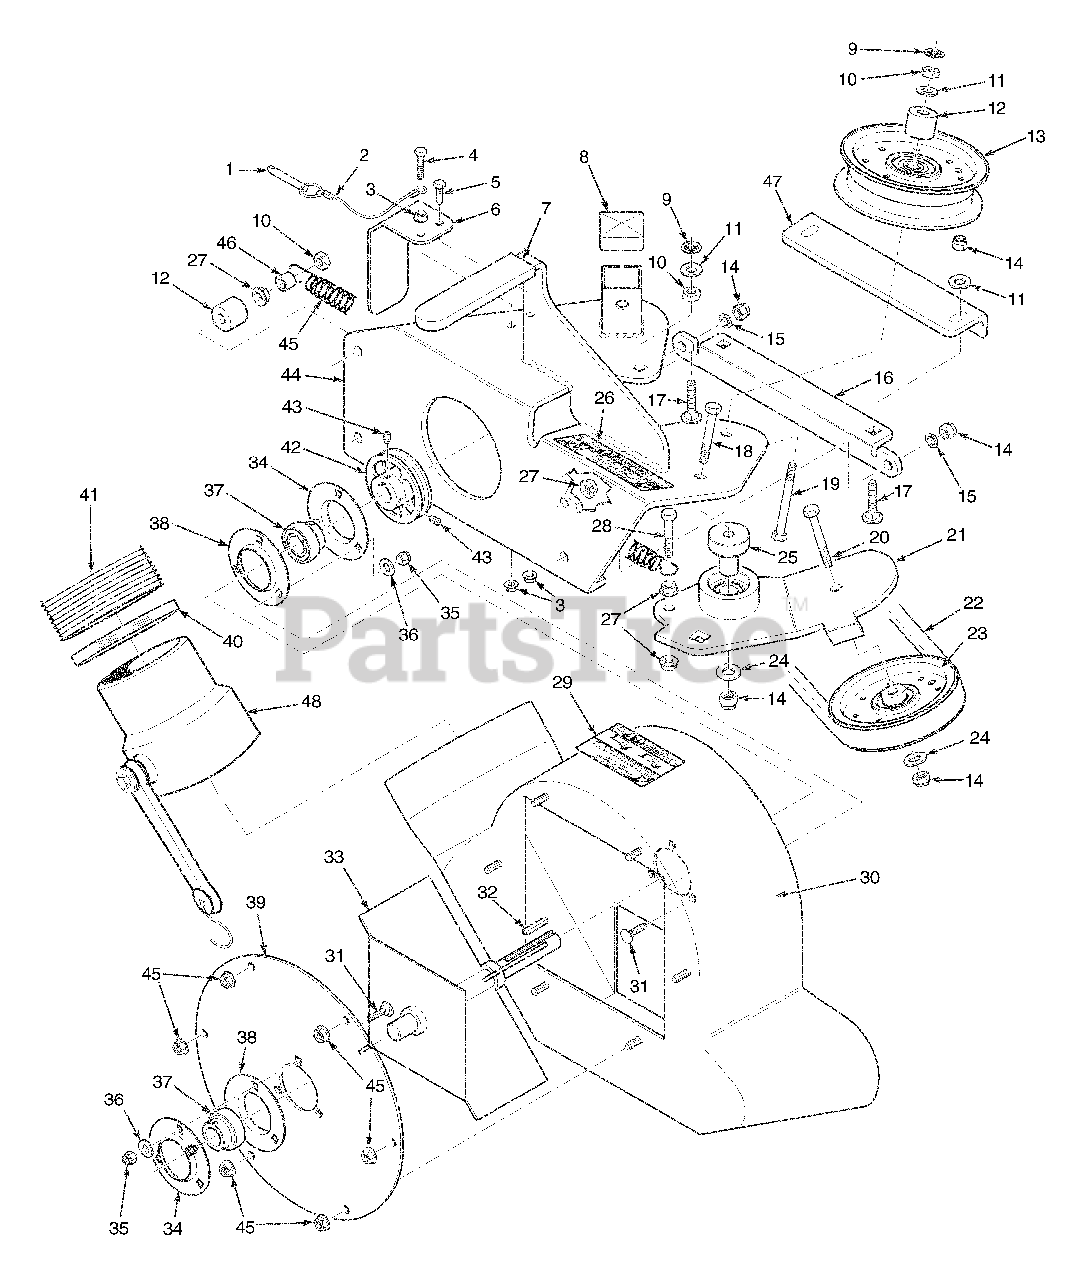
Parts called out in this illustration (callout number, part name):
1	Pin, Ring 2-1/4" Long
2	Lanyard, Deck Height Pin
3	Nut, Serr. Flange 1/4-20
4	Bolt, Hex Head 1/4-20 x 1-1/4"
5	Bolt, Hex Head 1/4-20 x 3/4"
6	Belt Cover, Rear
7	Grip, Blower Lever
8	Cap, Square
9	Nut, Push On 3/8 Thread
10	Lock Nut, 3/8-16
11	Flatwasher, 3/8-.391 x .938 x .105
12	Spacer
13	Pulley, Idler 4" Dia. - 61" Cutter Deck
14	Nut, Elastic Stop 3/8-16
15	Lockwasher, 3/8-16
16	Plate, Catch Mounting
17	Bolt, Carr. 3/8-16 x 1-1/2"
18	Bolt, Hex Head 3/8-16 x 2-1/4" - 61"
19	Bolt, Hex Head 3/8-16 x 3-1/2"
20	Bolt, Hex Head 3/8-16 x 1-3/4"
21	Idler Arm Assembly, GC-STC 61"
22	Belt, GC-STC 61"
23	Pulley, 4" O.D., GC-STC 61"
24	Washer, 3/8 Hardened
25	Pivot, Idler - 61"
26	Decal, Belt Cover
27	Nut, Serr. Flange 3/8-16
28	Bolt, Hex Head 3/8-16 x 1-1/2 Gr. 8
29	Decal, Danger
30	Blower Housing Assembly
31	Bolt, Carr. 5/16-18 x 3/4" Gr. 5
32	Key, 1/4 x 1/4 x 1-1/2"
33	Fan Weldment
34	Bearing Assembly
35	Nut, Elastic Stop 5/16-18
36	Flatwasher, 5/16-.344 x .688 x .065
37	Cover, Blower Housing
38	Clamp, 8-5/8" Max Dia.
39	Hose, 8.00" Dia. x 56.00" Long
40	Pulley, 4-3/4" O.D. - 1" Bore
41	Set Screw, 5/16-18 x 3/8"
42	Frame, Blower Mount - 61"
43	Spring, Main Drive
44	Spacer
45	Nut, Serr. Flange 5/16-18
46	Adapter w/Strap
47	Plate, Blower Catch
